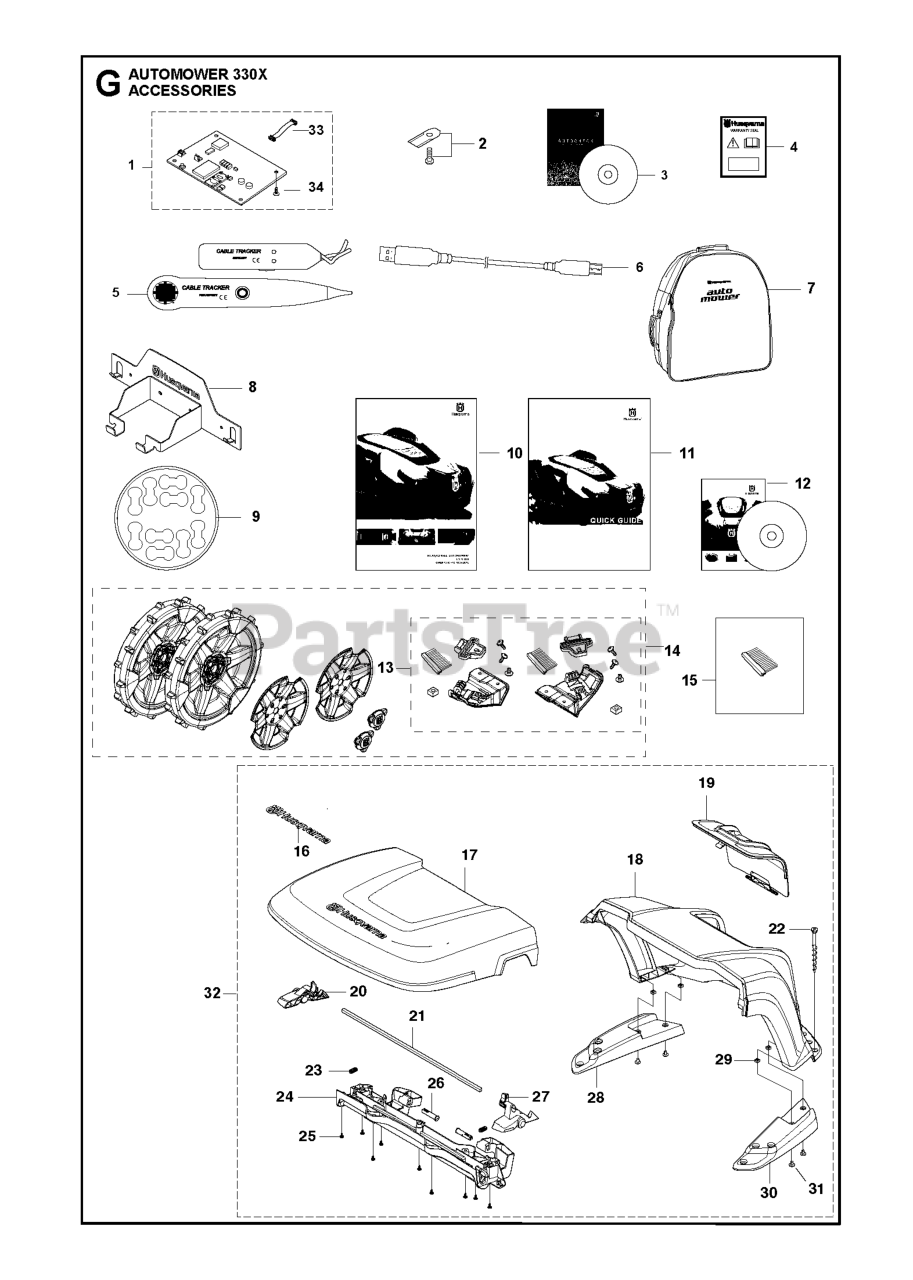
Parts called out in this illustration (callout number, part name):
2	BLADE SET 300 PCS. CARBON STEE
2	BLADE KIT HUSQVARNA 9 PCS 50HR
2	BLADE SET 45 PCS
3	DVD AUTOCHECK EXP SERVICE
4	LABEL WARRANTY SEAL KIT 10 PK
4	LABEL WARRANTY SEAL DEALER
5	TEST EQUIPMENT
6	CABLE WHITE ALT GREY
9	STICKER CABLE MARKERS KIT 10PC
12	CD DVD MANUALS 305, 308, 310,
14	REAR WHEEL KIT W/ BRUSHES
16	DECAL.HUSQVARNA.210MM
17	KIT LID - AUTOMOWER HOUSE
18	COVER BASE P2 HOUSE
20	HANDLE RELEASE LEFT
22	SCREW KIT CS
23	SPRING SPRING CAP
25	SCREW 14MM
27	HANDLE RELEASE RIGHT
28	SUPPORT BASE LEFT
30	SUPPORT BASE RIGHT
31	SCREW IHPANM M6X25 4.6 ZP-BC
32	430/450 HOUSE KIT
34	SCREW 14MM
